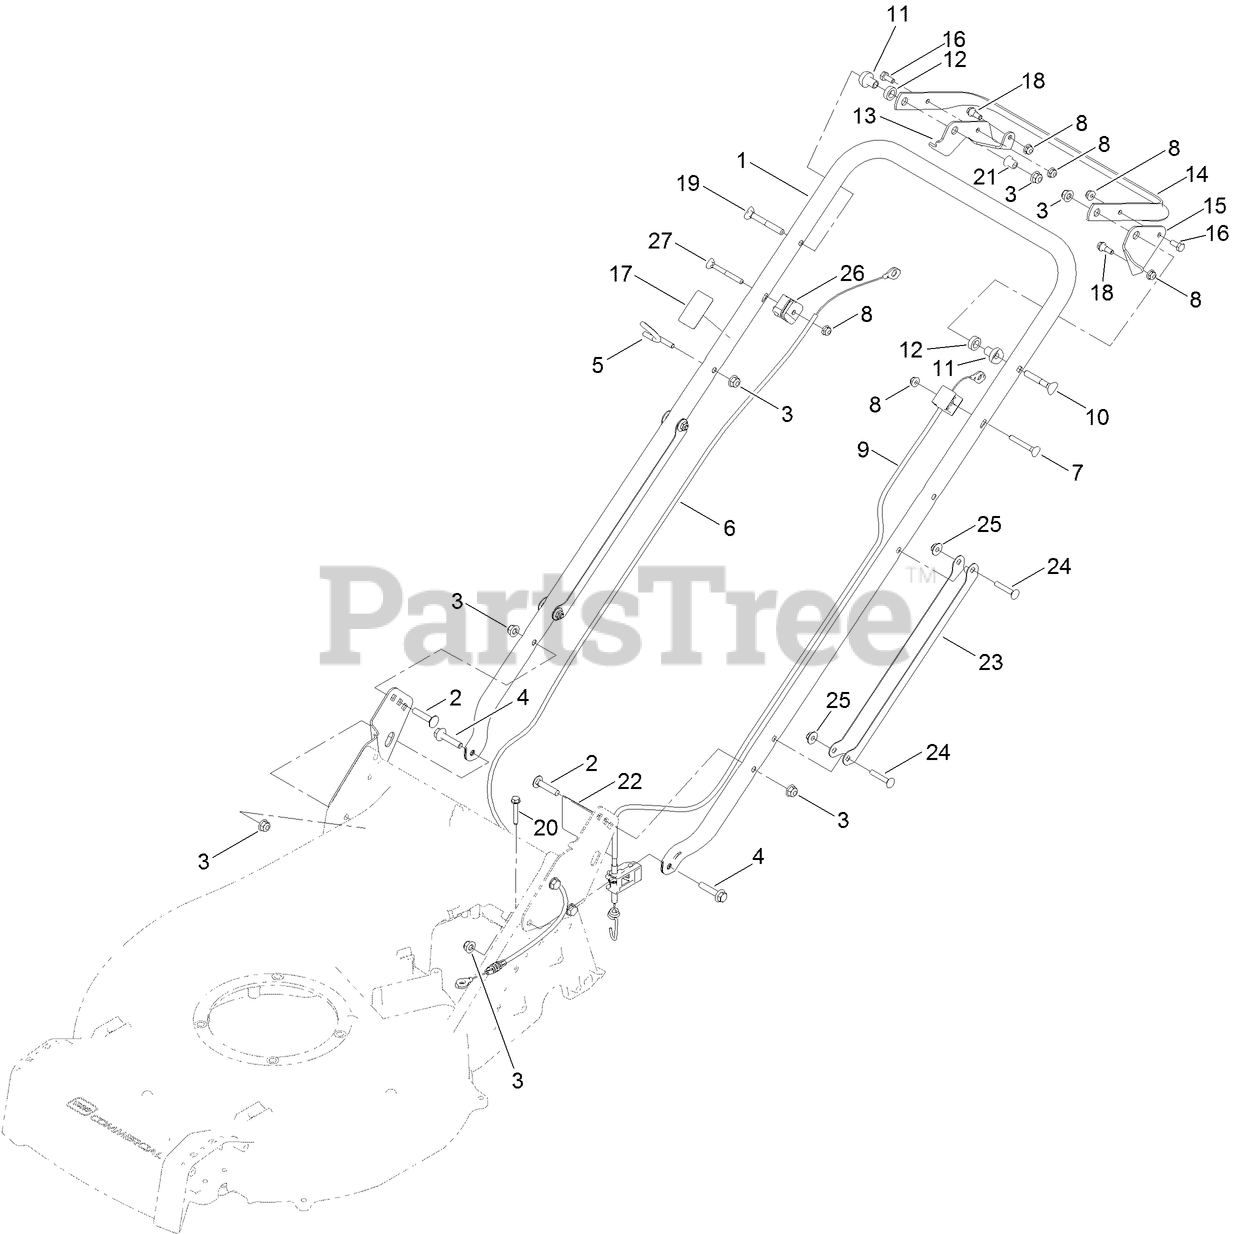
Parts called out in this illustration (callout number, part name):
2	BOLT-CARR
3	NUT-HF, NI
4	SCREW-HHF
5	GUIDE,ROPE
6	CABLE-BRAKE
7	SCREW
8	NUT-HF
9	CABLE-TRACTION
10	SCREW-HANDLE
11	SPACER-SUPPORT
12	SPACER-NYLON
13	BRACKET-CONTROL, BRAKE
14	BAR-CONTROL, ZONE START
15	LEVER-CONTROL, TRACTION
16	SCREW-HH
17	DECAL-PRIMER
18	BOLT-SHOULDER
19	SCREW-HANDLE
20	SCREW-HWH
21	SPACER
23	GUARD-CABLE, HANDLE
24	SCREW-CARR
25	NUT-HF
26	ANCHOR-CABLE
27	SCREW-HANDLE
